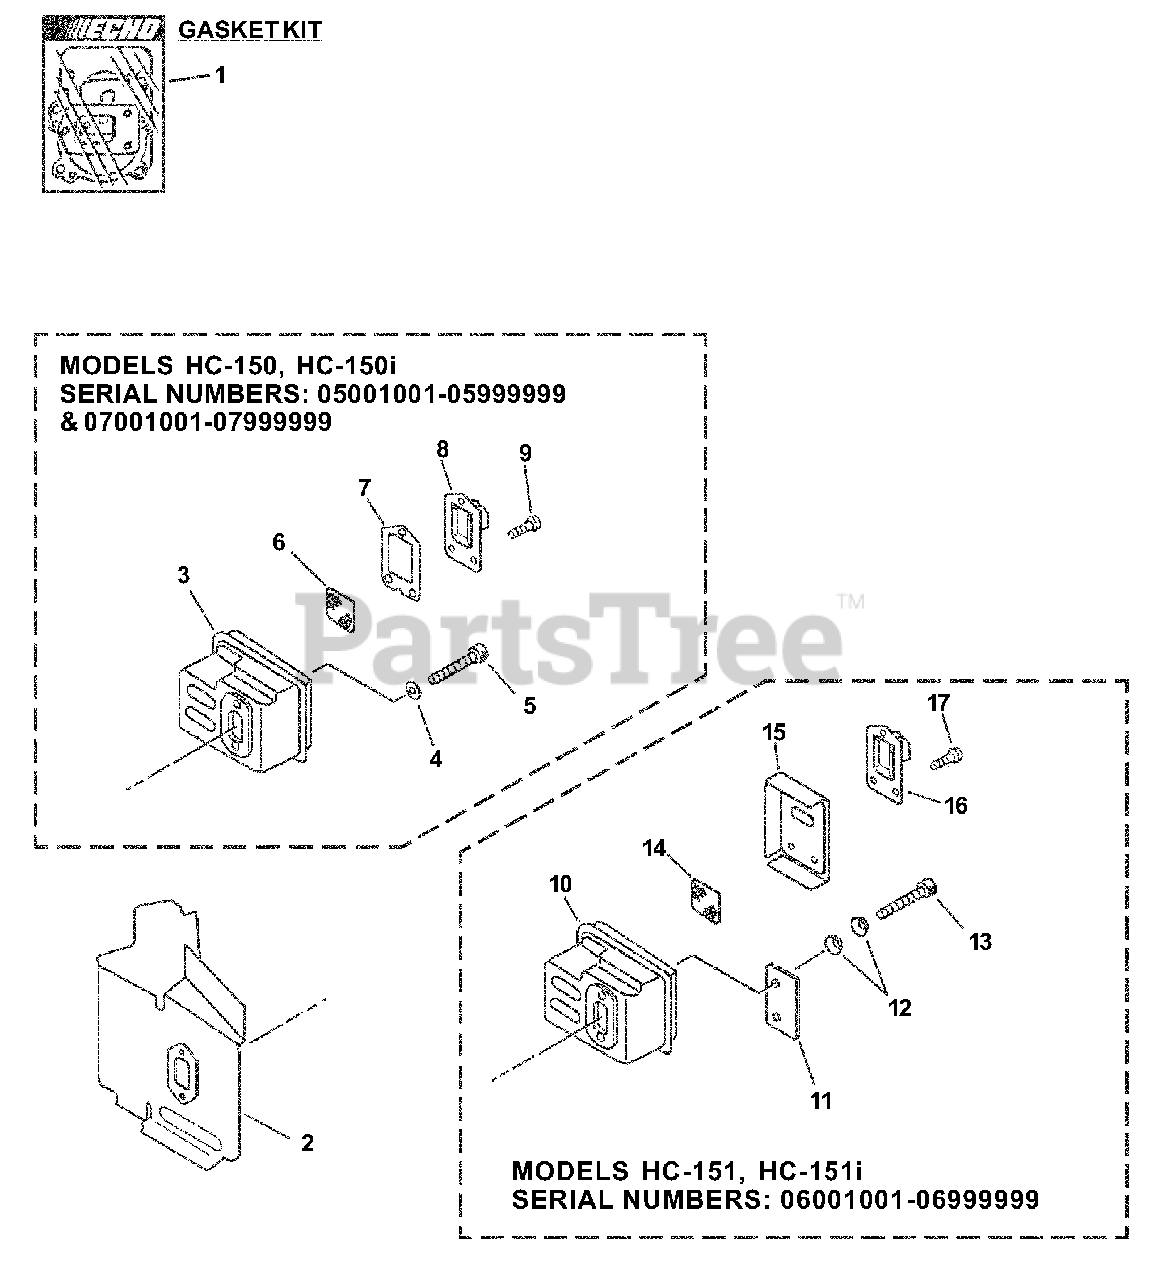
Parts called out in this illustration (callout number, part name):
1	GASKET KIT
2	SHIELD, EXHAUST
4	WASHER - 5
5	SCREW - 5X50
6	SCREEN, SPARK ARRESTOR
7	GASKET, EXHAUST
8	GUIDE, EXHAUST
9	SCREW - 4X10
10	MUFFLER
12	WASHER - CONICAL
13	SCREW - 5X55
14	SCREEN, SPARK ARRESTOR
15	GASKET, EXHAUST
16	GUIDE, EXHAUST
17	SCREW - 4X12
